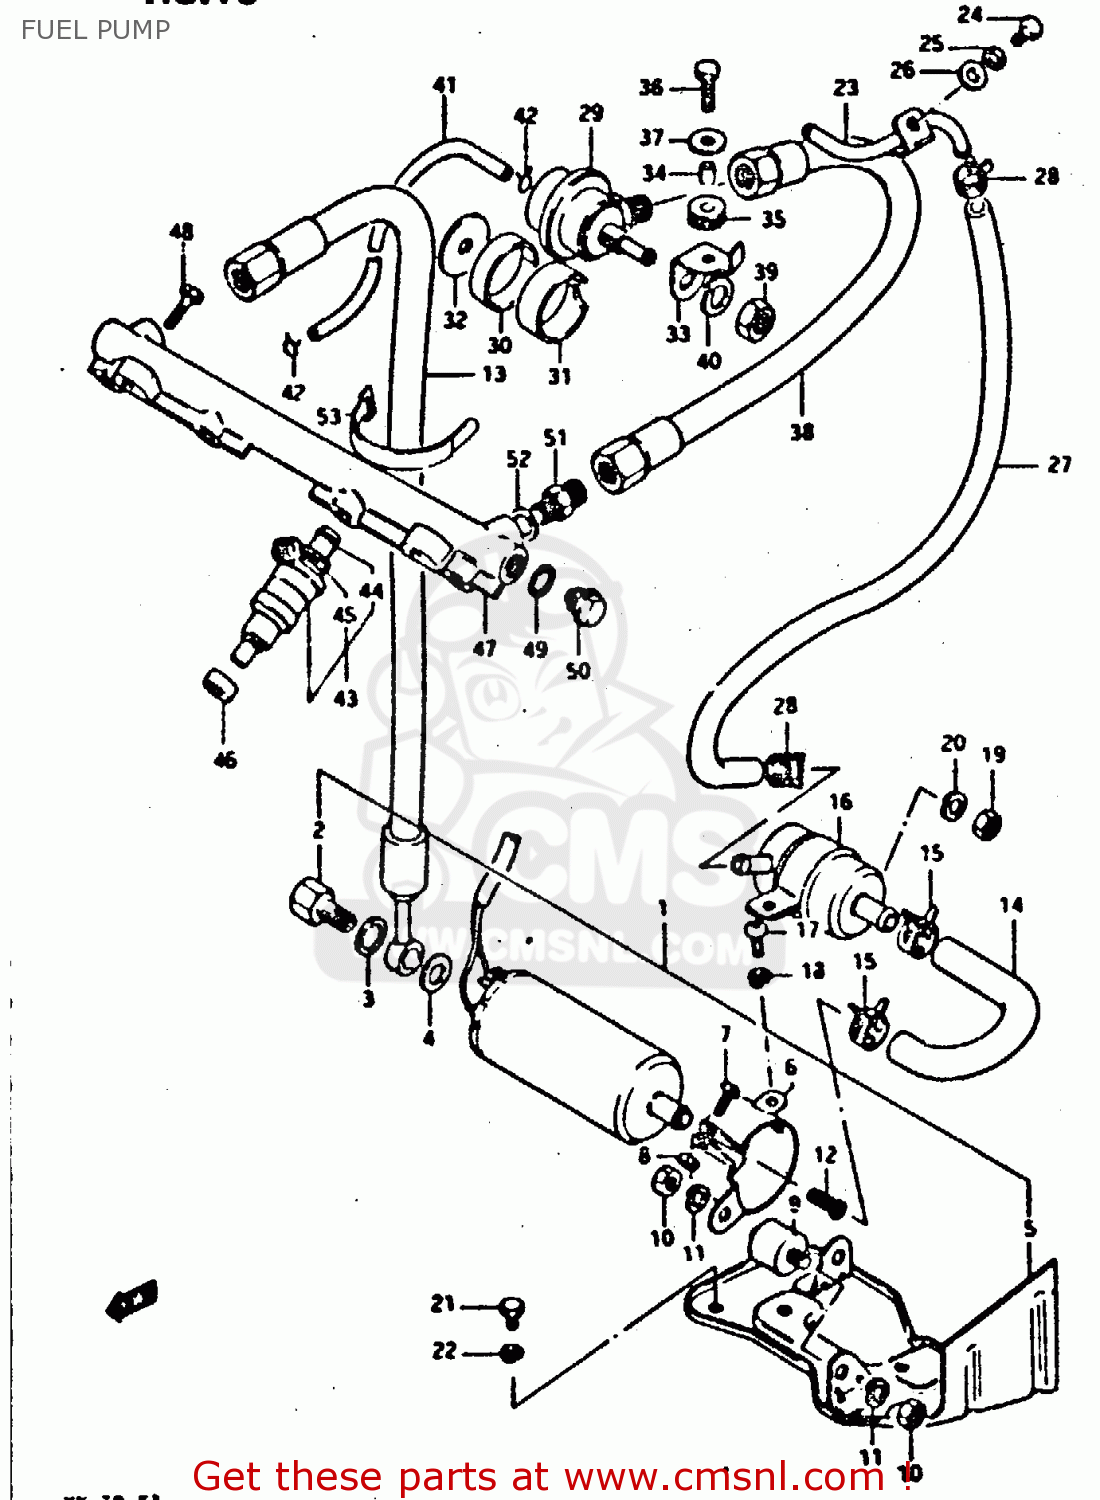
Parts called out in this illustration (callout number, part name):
1	PUMP ASSEMBLY,FUEL
2	NUT,FUEL PUMP
3	GASKET,FUEL PUMP
4	WASHER,FUEL PUMP
5	BRACKET,FUEL PUMP
6	CLAMP,FUEL PUMP
7	SCREW
8	NUT
9	CUSHION,FUEL PUMP
10	NUT
11	LOCK WASHER
12	FILTER
13	HOSE, OUTLET
14	HOSE,FUEL PUMP INLET N
15	CLAMP
16	FILTER ASSEMBLY,FUEL
17	SCREW 6X12
18	LOCK WASHER
19	NUT
20	LOCK WASHER
21	BOLT
22	LOCK WASHER
23	PIPE, PUMP INLET
24	BOLT
25	LOCK WASHER
26	WASHER
27	HOSE, PUMP INLET (2)
28	CLAMP
29	REGULATOR ASSEMBLY,FUEL PRESSURE
30	PROTECTOR,PRESSURE REGULATOR
31	PROTECTOR,PRESSURE REGULATOR
32	PROTECTOR,FUEL REGULATOR
33	BRACKET
34	SPACER(6.1X9X7.5)
35	CUSHION
36	BOLT
37	WASHER (6.5X20X1.2)
38	HOSE,FUEL PRESSURE REGULATOR
39	NUT 12MM
40	WASHER,LOCK 12
41	HOSE
42	CLAMP
43	INJECTOR ASSEMBLY,FUEL
44	O RING
45	GROMMET
46	SEAL RING,FUEL INJECTOR
47	HOLDER, INJECTOR
48	SCREW (6X25)
49	GASKET(14X20X1.5) (NAS)
50	PLUG(14X12)
51	BOLT UNION
52	GASKET(12X16.5X1.5) (NAS)
53	CLAMP
